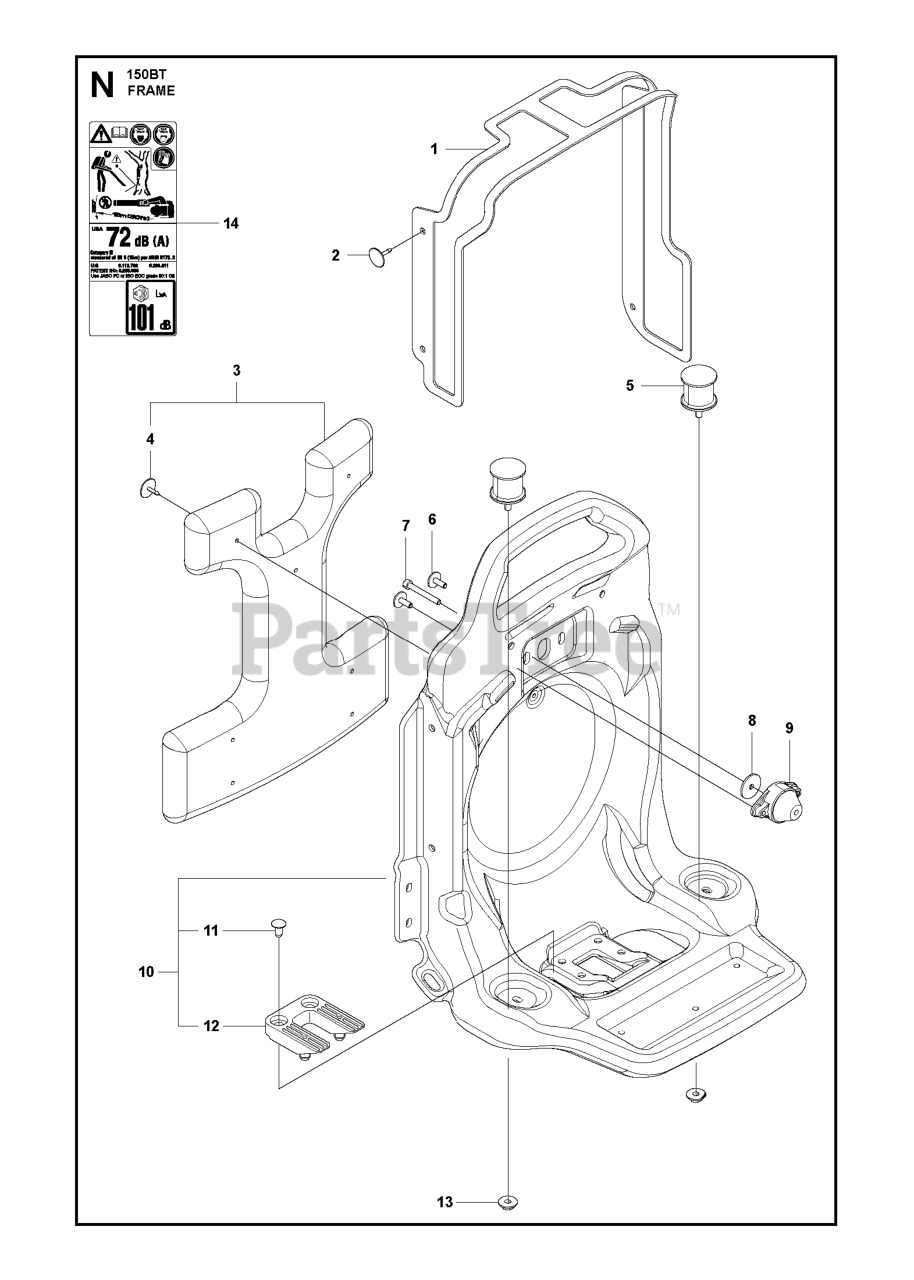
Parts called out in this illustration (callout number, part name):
2	CLIP
3	PAD COMP
8	WASHER
9	DAMPER UPPER
11	CLIP
14	LABEL CAUTION
